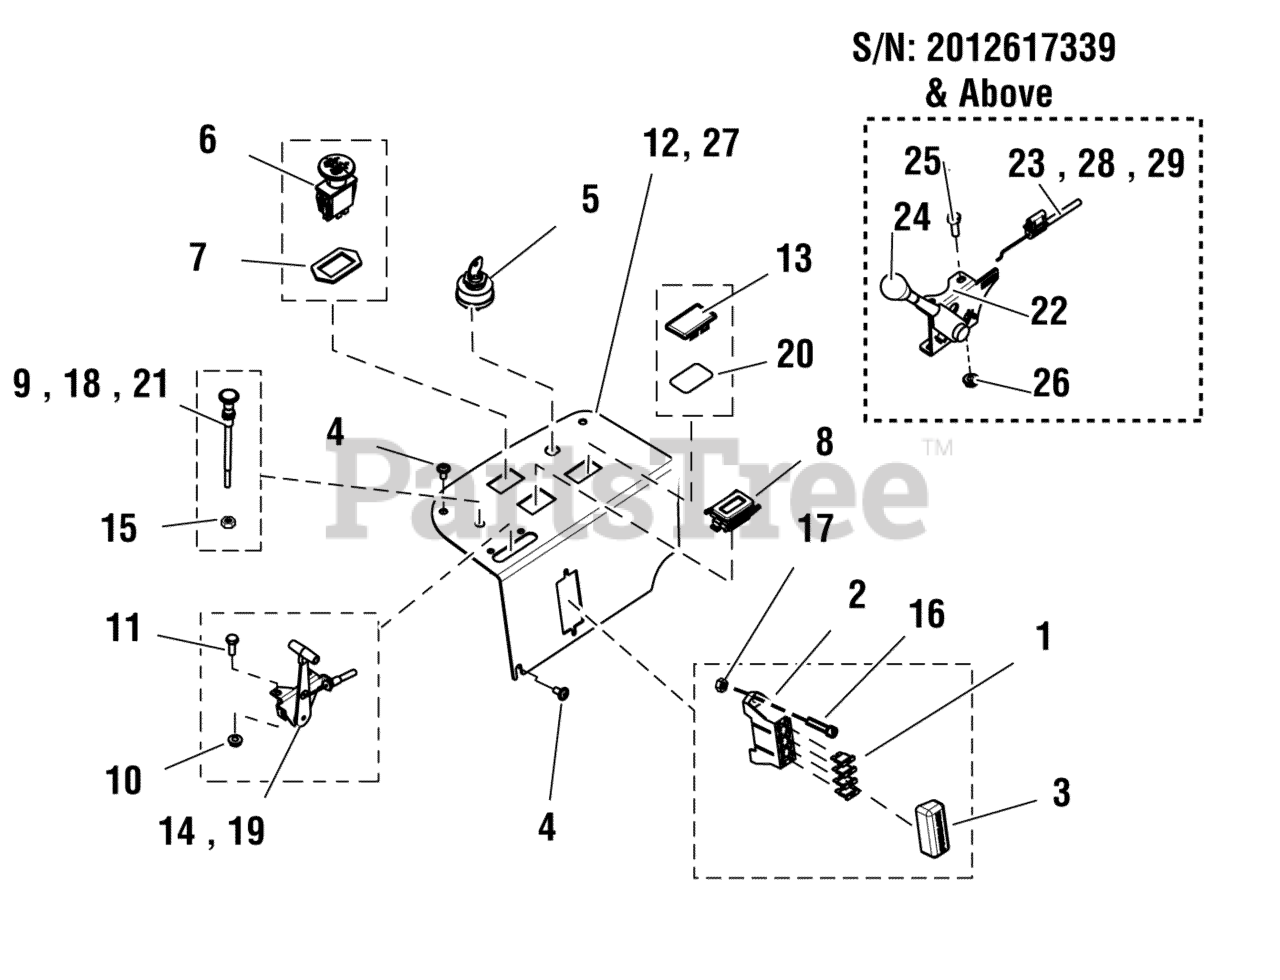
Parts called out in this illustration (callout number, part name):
1	FUSE, ATO 20 AMP
2	FUSE, BLOCK
3	COVER, VINYL FUSEBLOCK
4	SCREW, 1/4-20 X 1/2" ALLEN BH
5	SWITCH, IGNITION, 6 POST
6	SWITCH, BLADE ENGAGEMENT
7	RING, SWITCH RETAINER
8	HOUR METER
9	CABLE, CHOKE CONTROL, 47"
10	NUT, 1/4-20 HEX SERR. FLANGE
11	BOLT, 1/4-20 X 3/4" GD5 YZ
12	PLATE, CONTROL PANEL, IS2000Z - BLACK
13	PLUG, .820X1.44 HOLE, BLACK PLASTIC
14	CABLE, THROTTLE CONTROL, 45"
15	NUT, 3/8 - 24 HEX
16	SCREW, #10-24 X 2" ROUND PHILLIPS
17	NUT, #10-24 HEX NYLON LOCK
18	CABLE, CHOKE CONTROL, 56", DETENTED
19	CABLE, THROTTLE CONTROL, 48"
20	O-RING, 7/8" ID X 1/16"
21	CABLE, CHOKE CONTROL, 51" (Z)
22	LEVER, THROTTLE CONTROL, HEAVY-DUTY
23	CABLE, THROTTLE, 42"
24	THROTTLE CONTROL HANDLE/KNOB
25	SCREW, #10-24 X 3/4"
26	NUT, #10-24 HEN NYLON LOCK
27	PANEL, CONTROL, IS2000Z
28	CABLE, THROTTLE 47"
29	CABLE, THROTTLE, 52"
